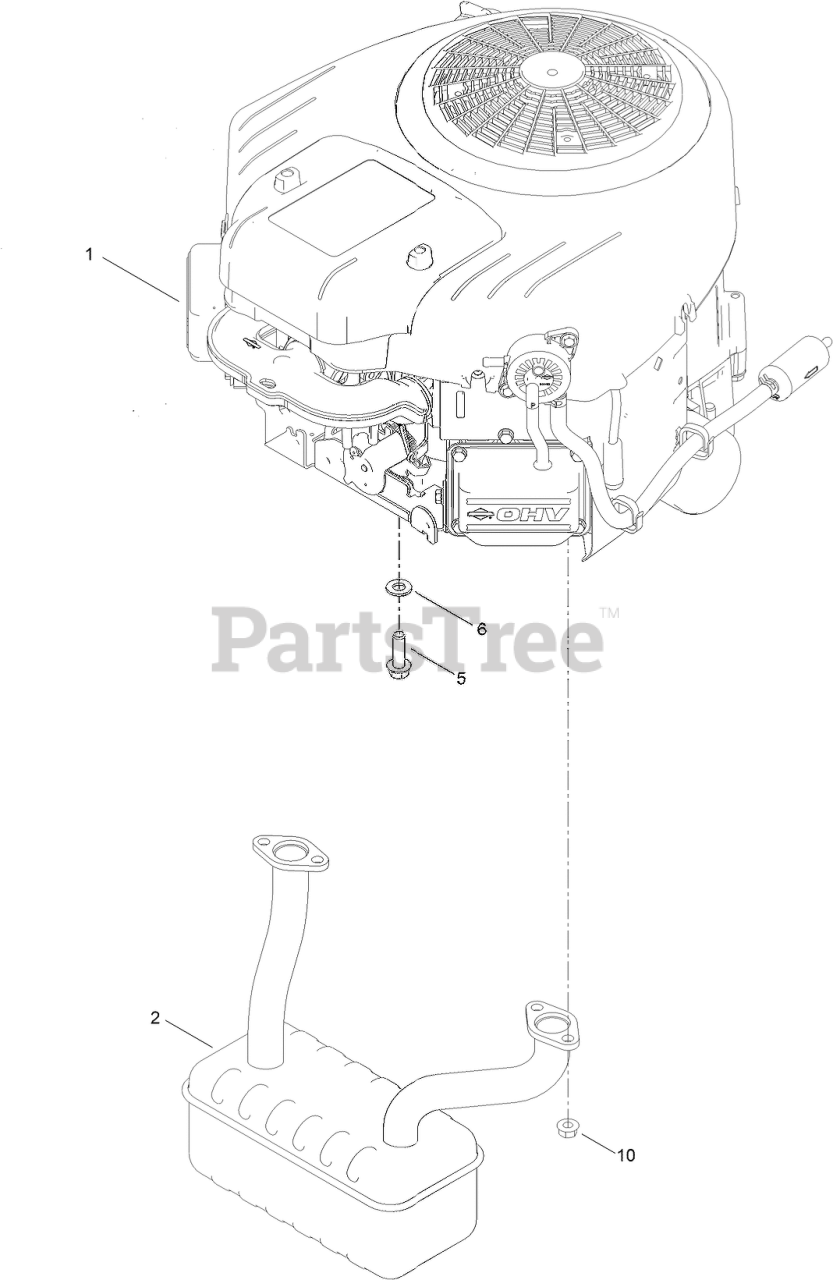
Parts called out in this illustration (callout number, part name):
1	ENGINE - BS EXI
2	MUFFLER
5	SCREW-THD
6	WASHER-FLAT
10	NUT-HF
